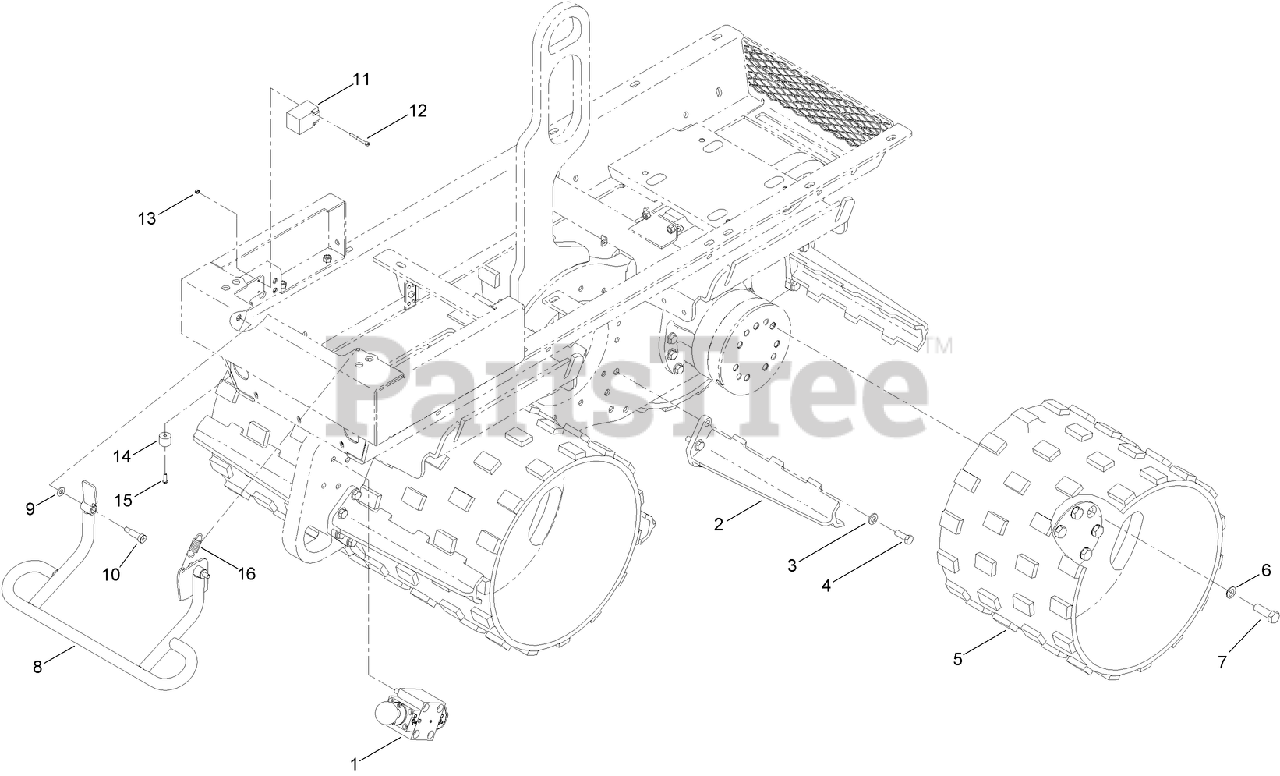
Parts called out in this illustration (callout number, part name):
1	BRAKE PARKING ASM
2	SCRAPER-DRUM, WIDE
3	WASHER-FLAT
4	SCREW-HH
5	DRUM-WIDE
6	SPACER-DRUM
7	SCREW-HH
8	BAR-SAFETY
9	WASHER-FLAT
10	SCREW-HSBH
11	SWITCH-PROXIMITY
12	SCREW-HSH
14	BUMPER-BAR, SAFETY
15	SCREW-HSBH
16	SPRING-EXTENSION
